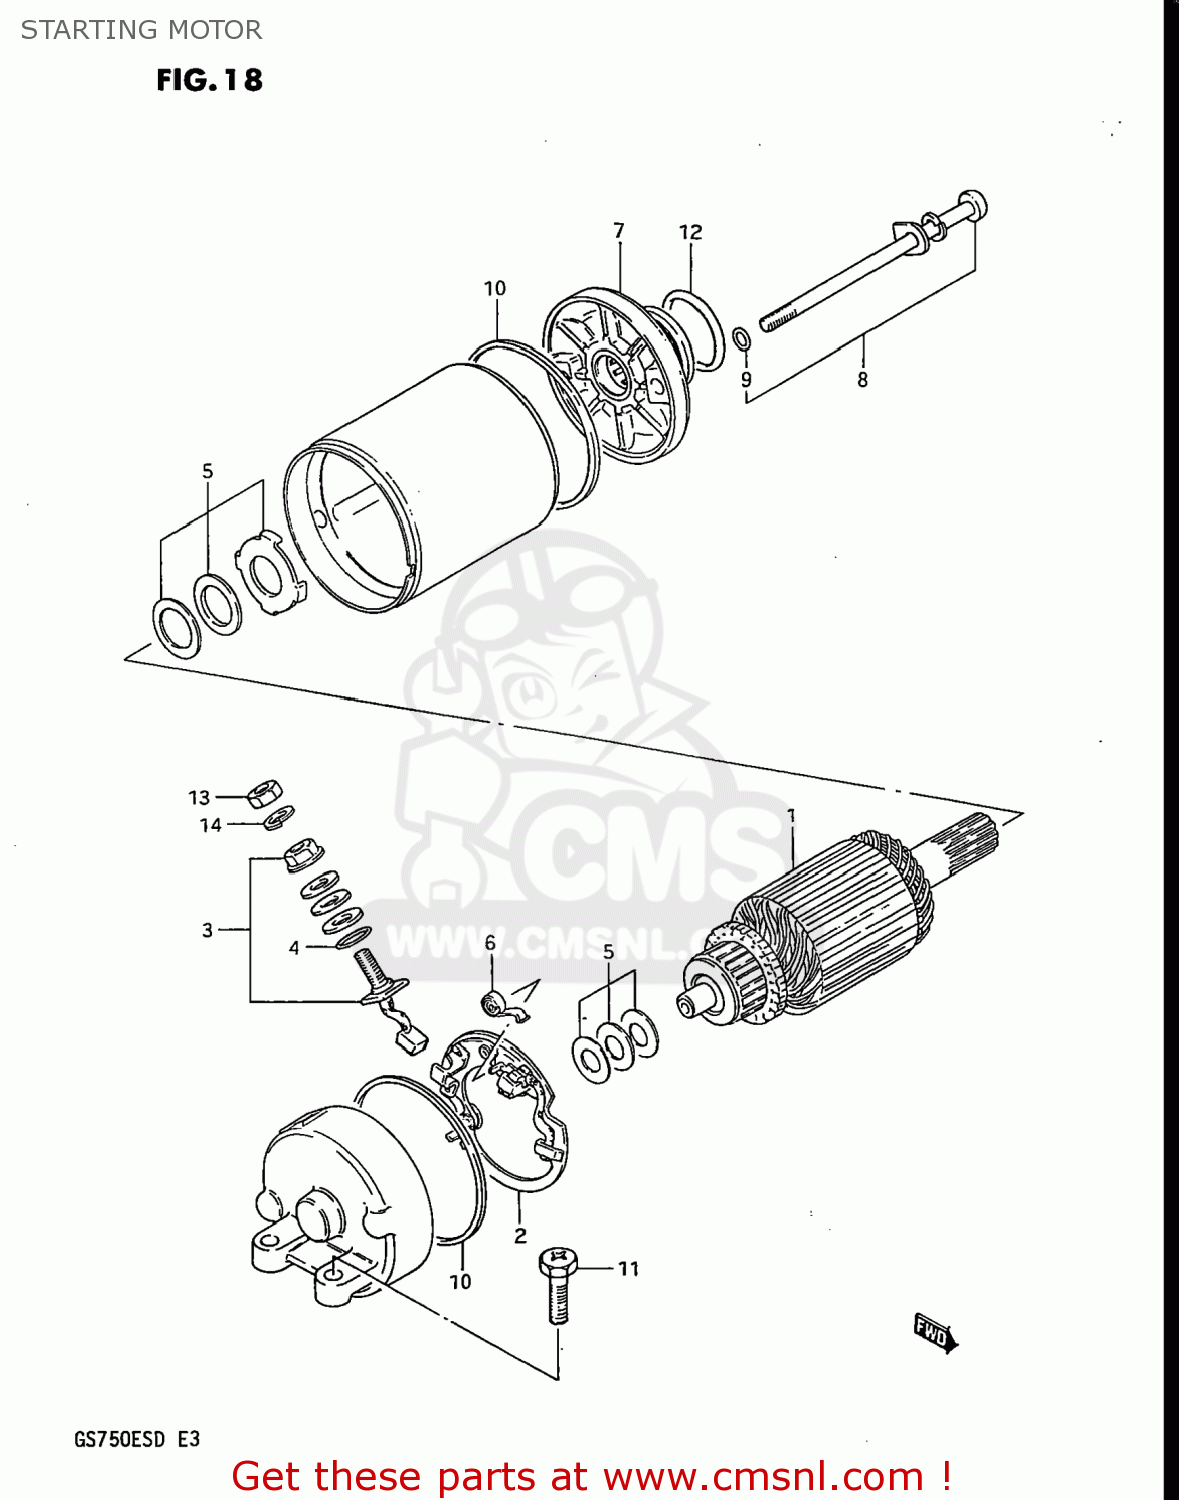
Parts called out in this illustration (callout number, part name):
1	ARMATURE
2	HOLDER SET,BRUSH(-)
3	TERMINAL SET,BRUSH,PLUS
4	O RING
5	SHIM SET,STARTING MOTOR
6	SPRING,BRUSH
7	BRACKET SET,STARTING MOTOR
8	BOLT SET,STARTING MOTOR
9	O RING
10	O RING
11	SCREW (6X25)
12	O RING(D:3,ID:24.5)
13	NUT 6MM
14	LOCK WASHER
